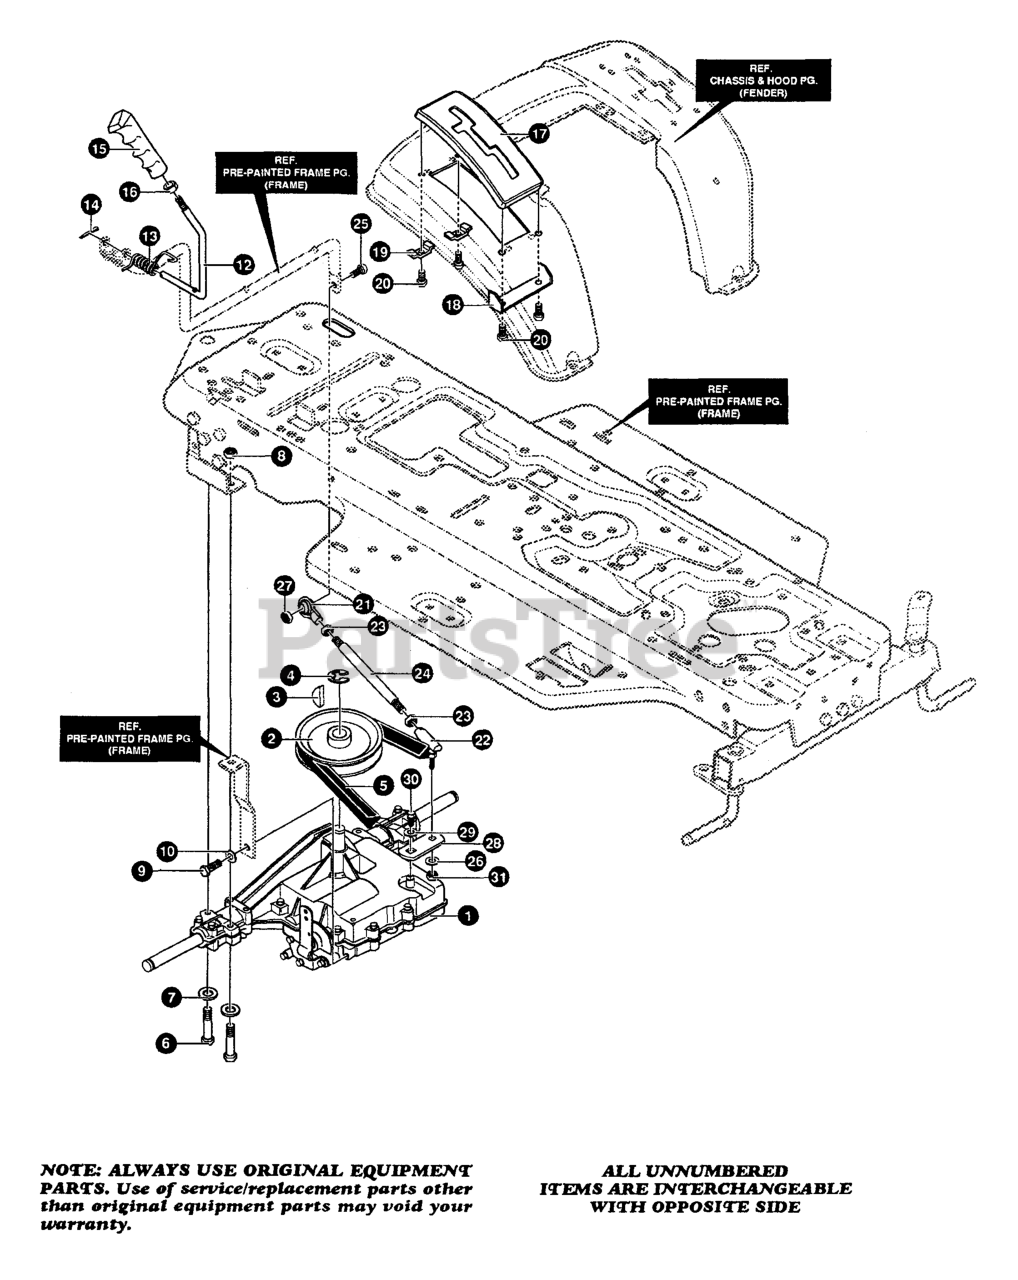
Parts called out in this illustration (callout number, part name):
1	TRANSAXLE **
2	PULLEY, 6.6
3	KEY, HI-PRO
4	RING, RETEX
5	BELT, V 4L 85.00
6	SCREW, 5/16-18 x 2.50
7	WASHER, FLAT .344 x .69 x .065
8	NUT, 5/16-18
9	SCREW, 5/16-18 x 0.75
10	WASHER, .328 X .60 X .09
12	LEVER, SHIFT UPPER
13	SPRING, TORSION
14	PIN, COTTER
15	KNOB, ROUND
16	NOT REQUIRED ON THIS UNIT
17	COVER, PLASTIC
18	BRACKET COVER
19	CLAMP, SPRING
20	SCREW, 1/4-15 x .441.53
21	BALL JOINT, RH 3/8-24
22	BALL JOINT, 3/8 THD SHORT STUD
23	NUT, 3/8-24
24	SHIFT ROD
25	SCREW, 3/8-24 X 1.00
26	WASHER, .393 x .68 x .10
27	NUT, 3/8-24
28	BRACKET, SHIFT
29	WASHER, .750 X .250
30	SCREW, 1/4-28 X .75
31	NUT, 3/8-24
